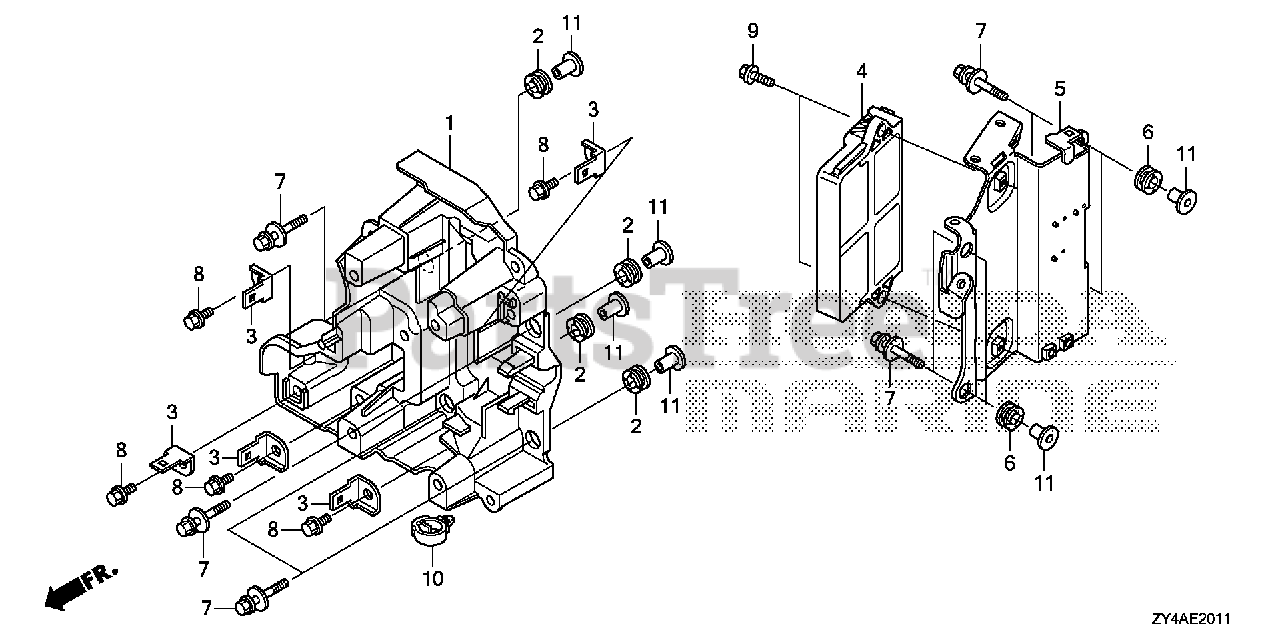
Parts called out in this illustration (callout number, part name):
1	CASE, ELECTRONIC PARTS
2	GROMMET, ELECTRONIC PARTS CASE
3	BRACKET, ALTERNATOR FUSE
4	CONTROL UNIT, ELECTRONIC
5	BRACKET, ECU
6	GROMMET, RELAY BRACKET
7	BOLT-WASHER (6X27) (CT200)
7	BOLT-WASHER (6X27)
8	BOLT, FLANGE (6X10)
9	BOLT, FLANGE (6X20)
10	CLIP, WIRE HARNESS (25MM)
11	COLLAR, MODULE IGNITION CONTROL CASE (CDI)
